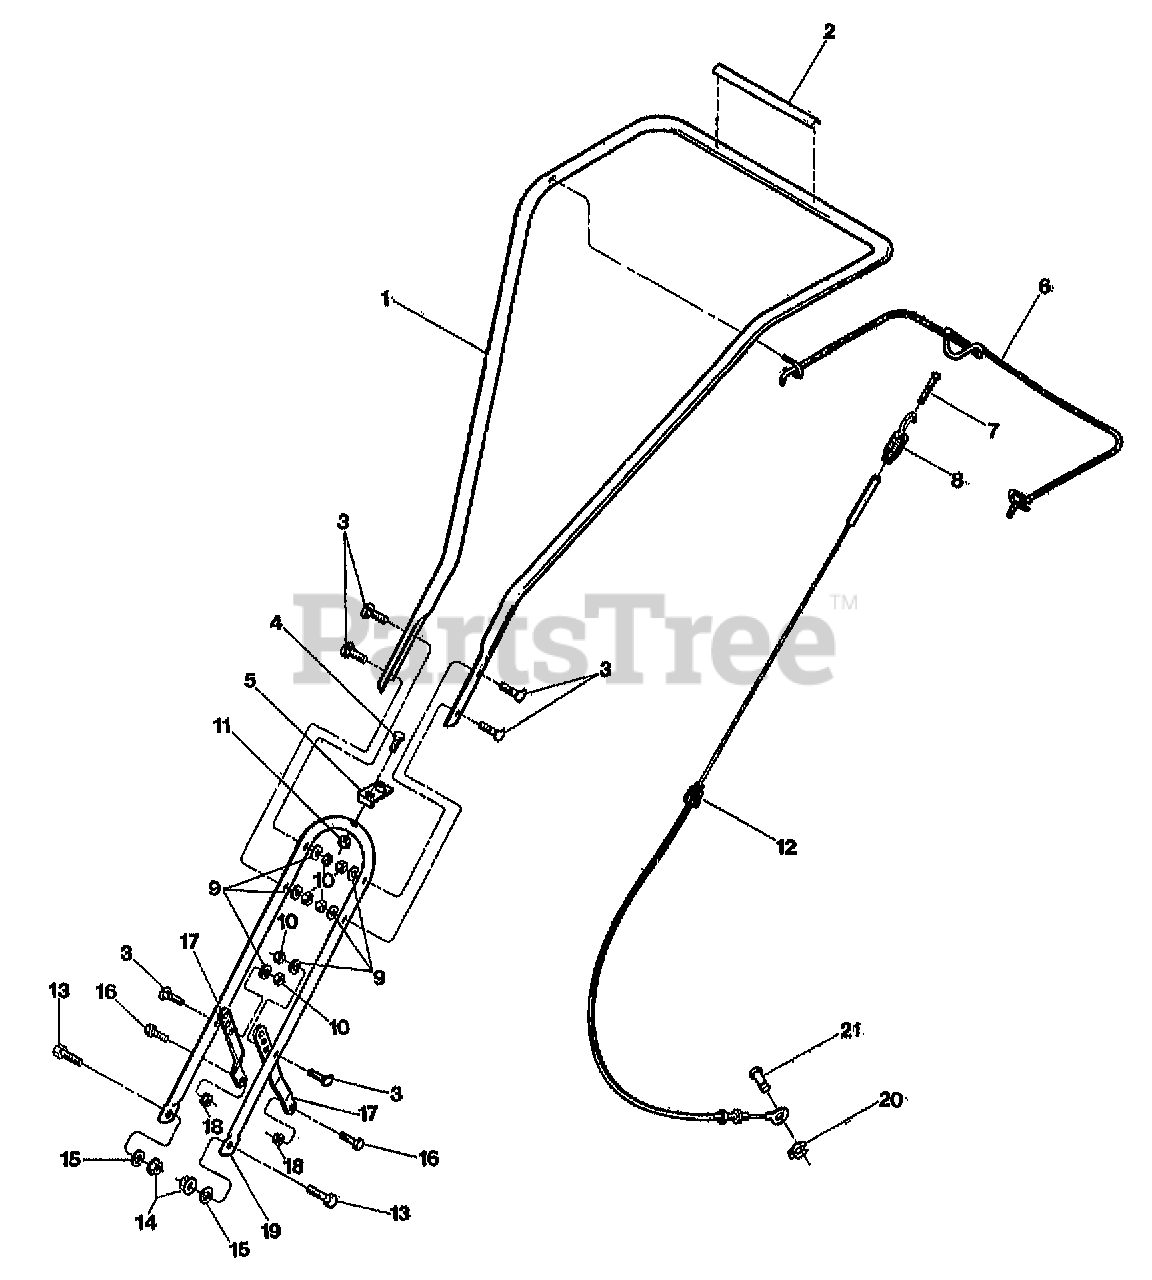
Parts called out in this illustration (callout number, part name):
1	HANDLEBAR-UPR W/DECAL
2	DECAL-FWD.CLUTCH LEVER
3	SCR-CUR.H.5/16X1 1/2
4	SCR-HH 1/4-20X1.25
5	TAB-CONDUIT MOUNT
6	BAIL-FWD. DRIVE PNT
7	SCR-SLOT.H.10-24X2
8	ASSM-SPRING CABLE
9	WASHER-LK .312 ZP
10	NUT-HEX 5/16-18 ZP
11	NUT-LK 1/4-20
12	ASSM-CONTROL CABLE
13	SCR-HH 3/8-16X.75 G5 ZP
14	NUT-LOCK 3/8-16 NYLON ZP
15	WASHER-FLAT 3/8 SAE
16	SCR-HH 5/16-18X.63 G5
17	LINK-H/BAR PNT
18	NUT-H/LK 5/16-18
19	HANDLEBAR-LWR PNT
20	RING-KLIP .188 DIA
21	PIN-CLEVIS CABLE
